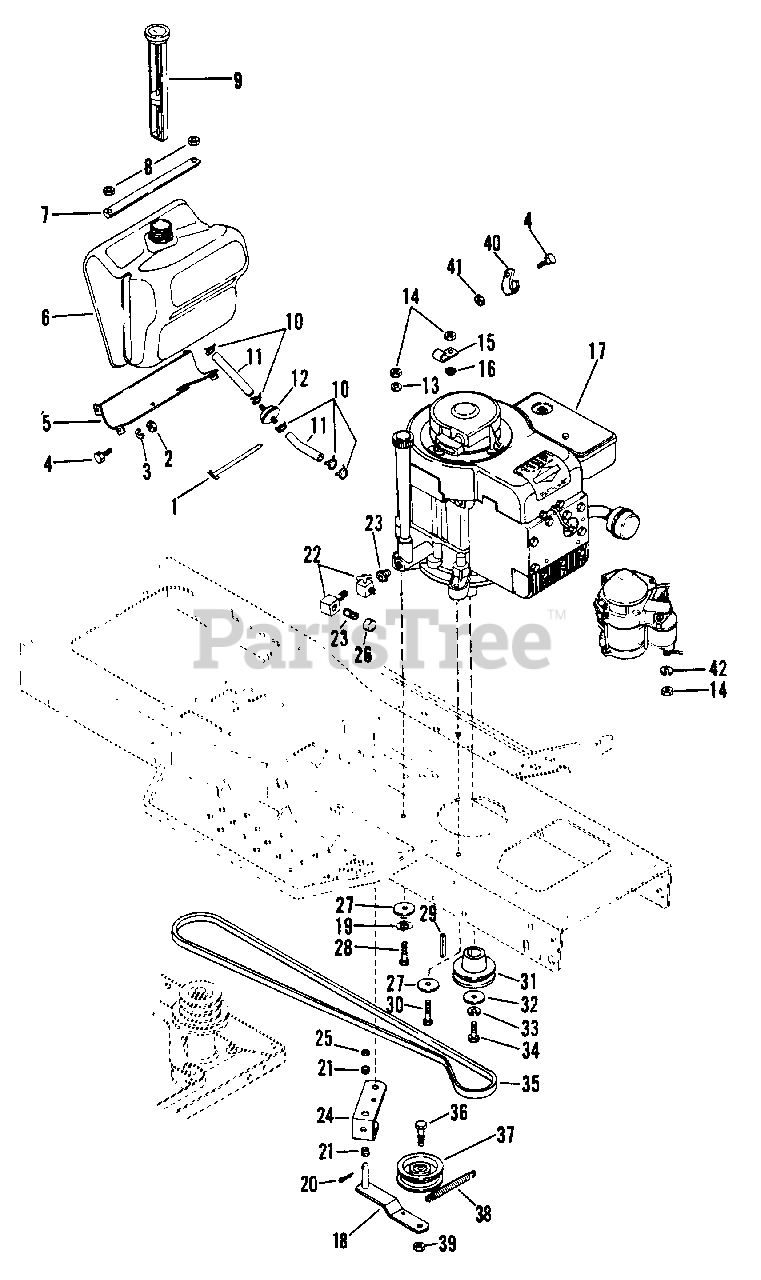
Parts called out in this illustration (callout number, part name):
1	TIE DOWN
2	NUT, HEX 1/4-20
3	WASHER, LOCK 1/4 REG.
4	BOLT, HEX 1/4-20X.50
5	SUPPORT, LOWER TANK
6	TANK, FUEL
7	STRAP, CLAMP
8	NUT, LOCK 1/4-20
9	GAUGE, FUEL
10	CLAMP, HOSE
11	LINE, FUEL
12	FILTER, FUEL
13	WASHER, FLAT .312X.734X.065
13	WASHER, LOCK 5/16 SP
14	NUT, LOCK 5/16-18
14	NUT, HEX M8-1.25
15	CLIP
16	WASHER, LOCK 5/16 EXT. TH. TYA
17	ENGINE, 12 H.P. B&S
17	ENGINE, 12.5 KAWASAKI
18	ARM, IDLER
19	WASHER, LOCK 5/16 SP
20	PIN, COTTER .125X1.00
21	BUSHING, FLANGE
22	ELBOW, DRAIN
22	FITTING, 90 DEGREE SPECIAL
23	PIPE, OIL DRAIN
24	PIVOT, IDLER
25	WASHER, FLAT .406X.812X.065
26	CAP, PIPE
26	CAP, HEX
27	WASHER, FLAT .312X1.62X.135
28	BOLT, HEX 5/16-18X1.50
28	BOLT, HEX M8X1.25X40MM
29	KEY, SQUARE .25X2.0
30	BOLT, HEX 5/16-18X1.75
30	BOLT, HEX M8X1.25X25MM
31	PULLEY, ENGINE
31	SHEAVE, ENGINE
32	WASHER, FLAT .563X1.375X.109
33	WASHER, LOCK 7/16 SP HEAVY
34	BOLT, HEX 7/16-20X1.00
34	SCREW, CAP M10X1.5X28
35	V-BELT
36	BOLT, HEX 3/8-16X1.50
37	IDLER
38	SPRING
39	NUT, LOCK 3/8-16
40	CLIP
41	NUT, LOCK 1/4-20
42	WASHER, LOCK 5/16 REG.
